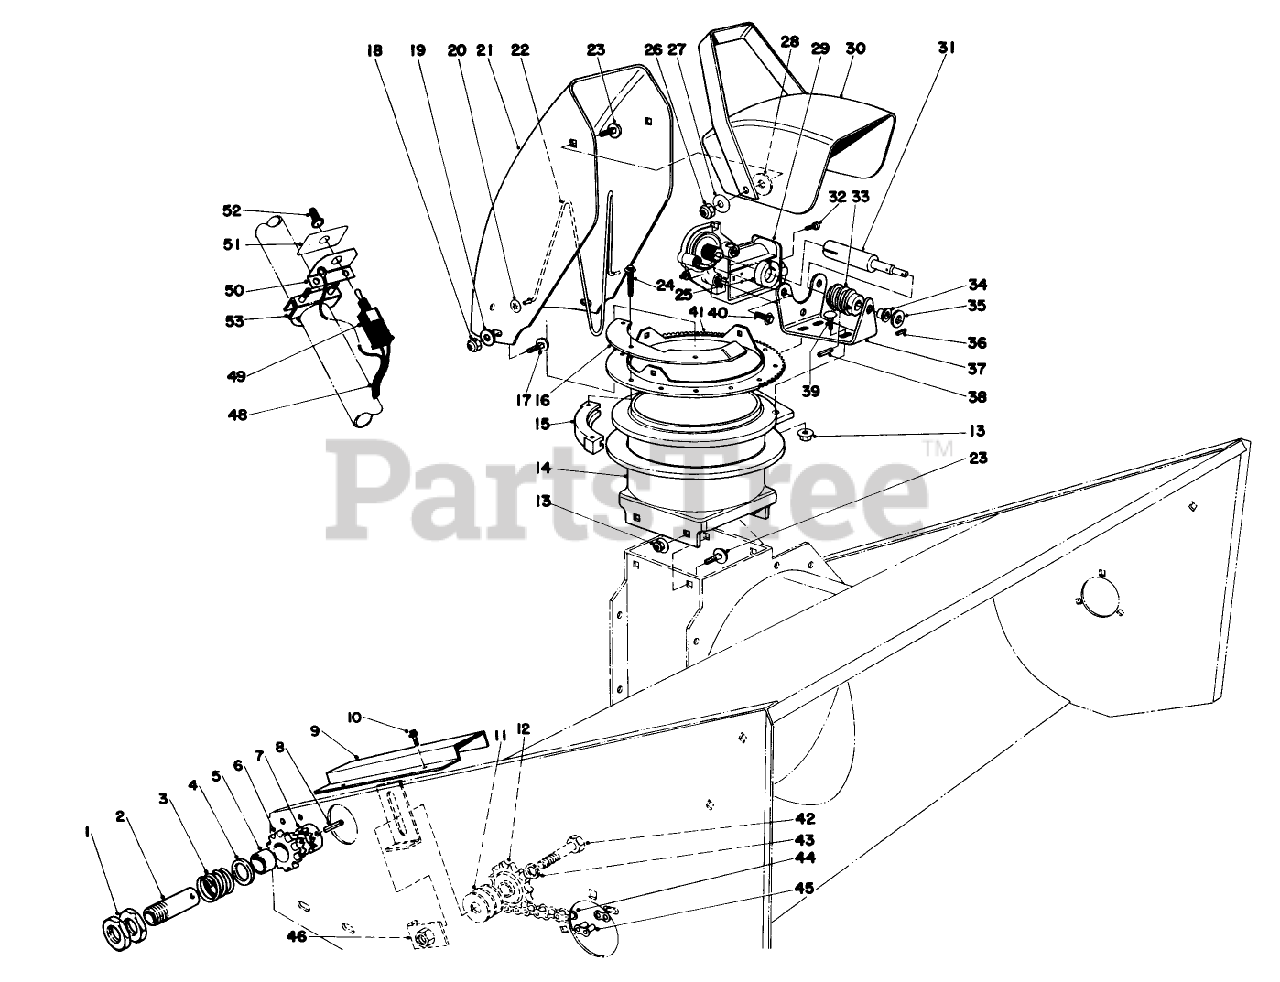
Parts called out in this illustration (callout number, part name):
1	Nut-Thin
2	Clutch Sleeve
3	Spring Compression
6	Clutch Sprocket
7	Clutch Collar
8	PIN-ROLL
9	Chain Cover
10	SCREW-HWHTF
11	WASHER-FLAT
12	IDLER SPRKT (60016)
13	NUT-HHF, WHIZ
14	Chute Transition
15	RETAINER-CHUTE
16	Stop-Chute Rotator
17	SCREW-CARR
18	Locknut
19	WASHER-PLAIN
20	NUT-PUSH
21	Upper Chute
22	WIRE-CHUTE
23	SCREW-CARR
24	SCREW-SPECIAL
25	SPLIT COLLAR
26	NUT-LOCK, CONE
27	WASHER-BELLEVILLE
28	WASHER-RUBBER
29	Gearmotor
30	Deflector
31	WORM GEAR SHAFT
32	SCREW-HSH
33	GEAR-WORM, CHUTE
34	FLANGE BSHG #FF-310-3
35	WASHER-FLAT
36	3/32 X 9/16 ROLL PIN
37	Motor Mount
38	PIN-SPRING
39	BOLT-CARR
40	SCREW-HHF
41	RING - CHUTE SWIVEL
42	SCREW-HH
43	WASHER-LOCK
44	ROLLER CHAIN (60023)
45	LINK-CHAIN
46	NUT PLATE WA (60095)
48	WIRE HARNESS
49	Toggle Switch Assembly (Incl. Ref. #50)
50	Toggle Switch Mount
51	DECAL
52	BOOT-SWITCH
53	CLAMP
